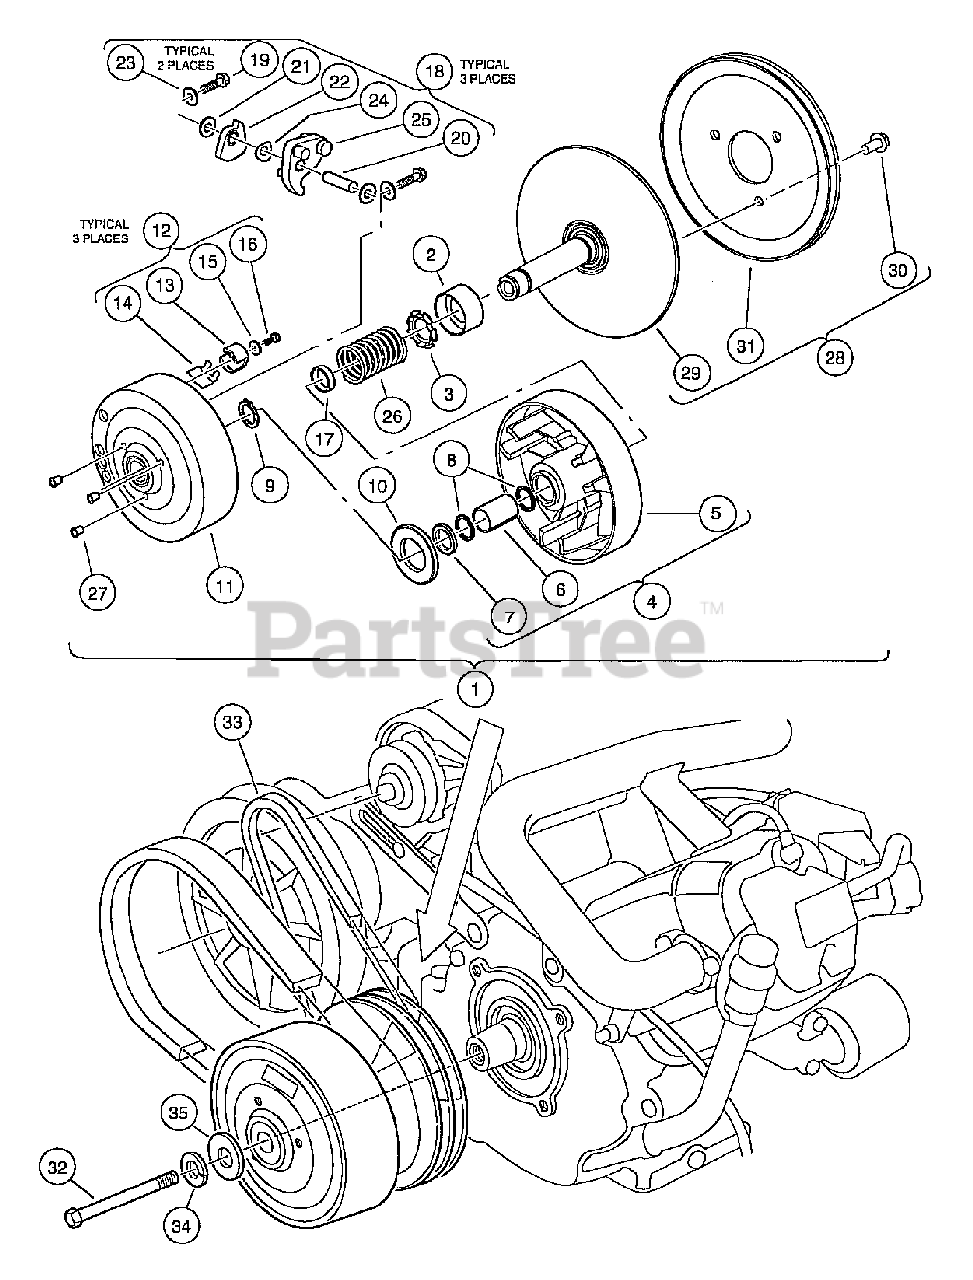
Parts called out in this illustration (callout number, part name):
1	Drive Clutch Assy. Fe 350/272
2	Bearing, Idler
3	Retainer, Spring
4	Movable-Face Assembly
5	Drive Clutch Movable Face
6	Bushing, Split
8	Ring, Spiral Backup
9	Ring, 0.810" Internal Retaining
10	Washer, Thrust
11	Drive Hub Assy, Drive Clutch
12	Kit, Drive Clutch Button
13	Driver, Drive Clutch
14	Spring, Drive Button
15	Washer, #10 Type A Flat
16	Screw, #10-24 X .50 Hex Head
17	Spacer, Fixed Face Shaft
18	Kit, Drive Clutch Weight
19	Screw, 1/4-20 X 1.00 Hex Head
20	Pin, 0.3752 X 1.50 Dowel
21	Washer, 0.38" Id Delrin Flat
22	Clutch Weight, Secondary
24	Washer, Wave
25	Weight, Primary
26	Spring, Drive Clutch
27	Cap Plug
28	Assembly, Fixed-Face Drive
29	Fixed Face Assembly, Drive Clutch
30	Screw, 5/16-18 X 0.75 Thread-Forming
31	Pulley, Clutch
32	Screw, 3/8-24 X 5.50 Hex Head
34	Washer, 3/8 Split Lock
35	Washer, 3/8 Type B Flat
